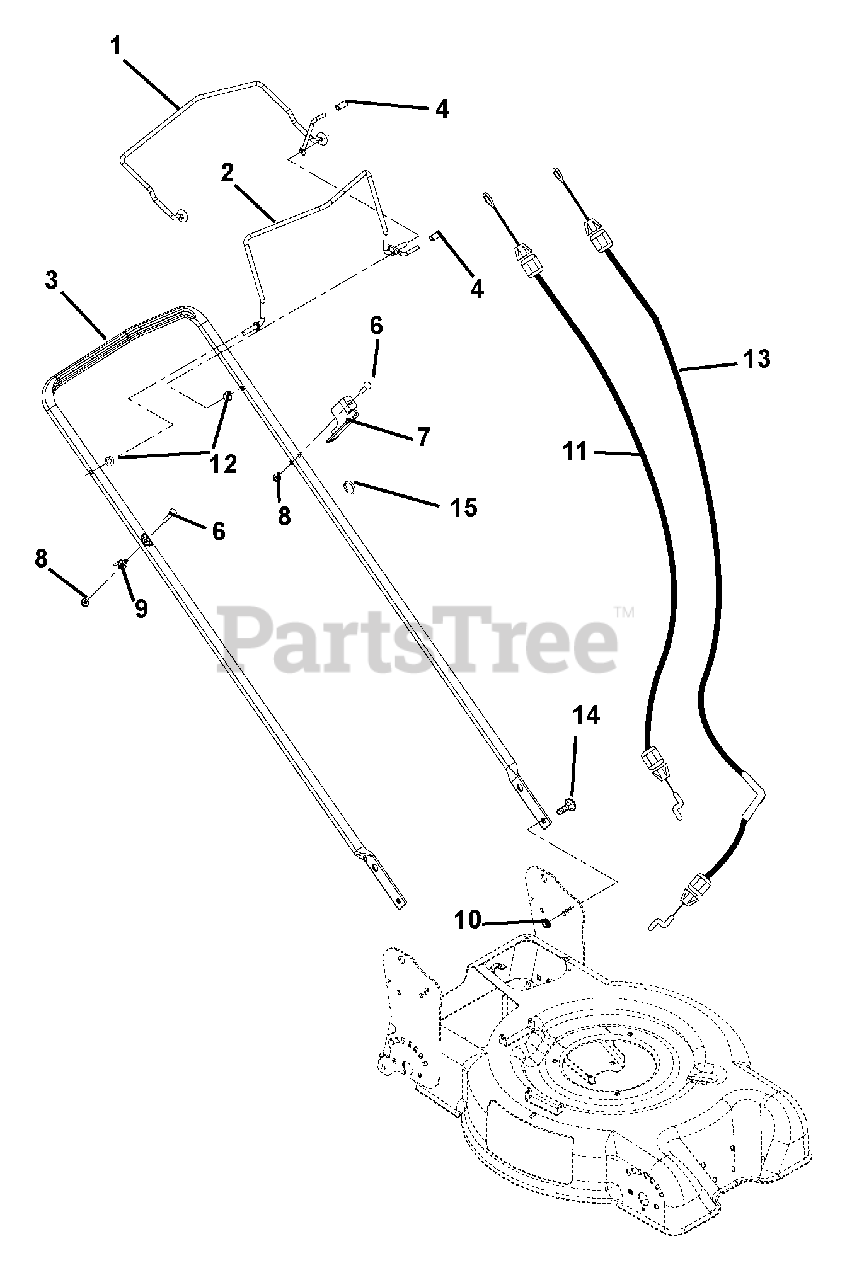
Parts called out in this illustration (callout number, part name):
1	BAIL, CLUTCH
2	BAIL, OPERATOR PRESENCE
3	HANDLEBAR, WBLM
4	CAP, VINYL, .25 ID
5	CAP, VINYL, .25 ID
6	BLT-RDHDXLSQNK.25-20X1.25 G5ZC
7	ANCHOR, CABLE
8	@NUT-LK-TOP-FLG .25-20 YWZC
9	GUIDE - PULLCORD
10	@NUT-SPNLK-FLG .312-18 YWZC
11	CABLE, OPERATOR PRESENCE
12	BSHG-FLG .325X.444X.440X.560
13	CABLE, TRACTION (ENTRY LEVEL)
14	@BLT-RHDSSQNK .31-18X.75 G5YZ
15	CONDUIT CLIP
